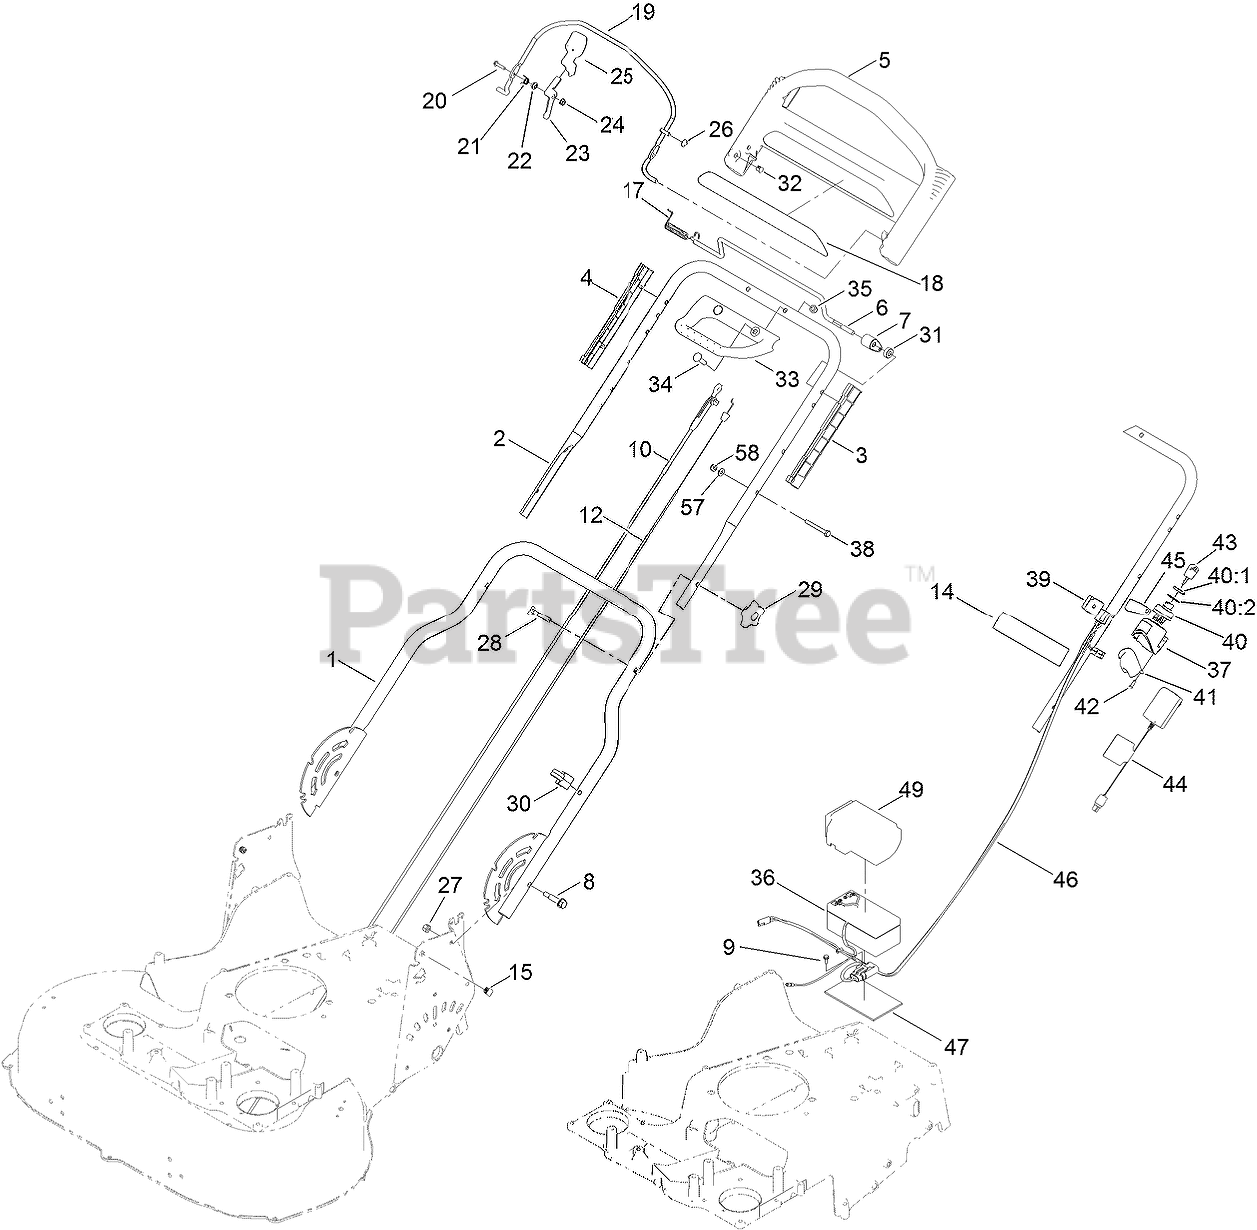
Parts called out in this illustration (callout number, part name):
1	HANDLE-LOWER
2	HANDLE-UPPER
3	GUIDE-LH
4	GUIDE-RH
5	HANDLE-CONTROL
6	BAR-CONTROL, TRACTION
7	LEVER-TRACTION
8	BOLT-SHOULDER, HHF
9	SCREW-TAPTITE
10	CABLE-BRAKE
12	CABLE-TRACTION
14	DECAL-WARNING
15	PLUG-SQUARE
17	SPRING-TORSION
18	DECAL-HANDLE
19	BAIL-BRAKE
20	SCREW-HWH
21	SPRING-TORSION
22	SPACER
24	NUT-HEX FLANGE
26	NUT-SPEED
27	NUT-HEX
28	SCREW-HANDLE
29	KNOB-HANDLE
30	GUIDE-CABLE
31	SPACER
32	PLUG-DOME
33	HANDLE-ASSIST, TRACTION
34	BOLT-CARRIAGE
35	NUT-ACORN
36	BATTERY-WET
37	HOUSING-SWITCH, KEY
38	SCREW-HH
39	ANCHOR-CABLE, UPPER
40	SWITCH-STARTER
40:1	NUT-HH
40:2	WASHER-LOCK
41	COVER-SWTCH
42	SCREW-PLASTIC, PPH
44	CHARGER, BATTERY (12V, CE)
45	DECAL-SWITCH, IGNITION
46	HARNESS-WIRE
47	FOAM-BATTERY
49	COVER-BATTERY
57	WASHER-FLAT
58	NUT-HEX
